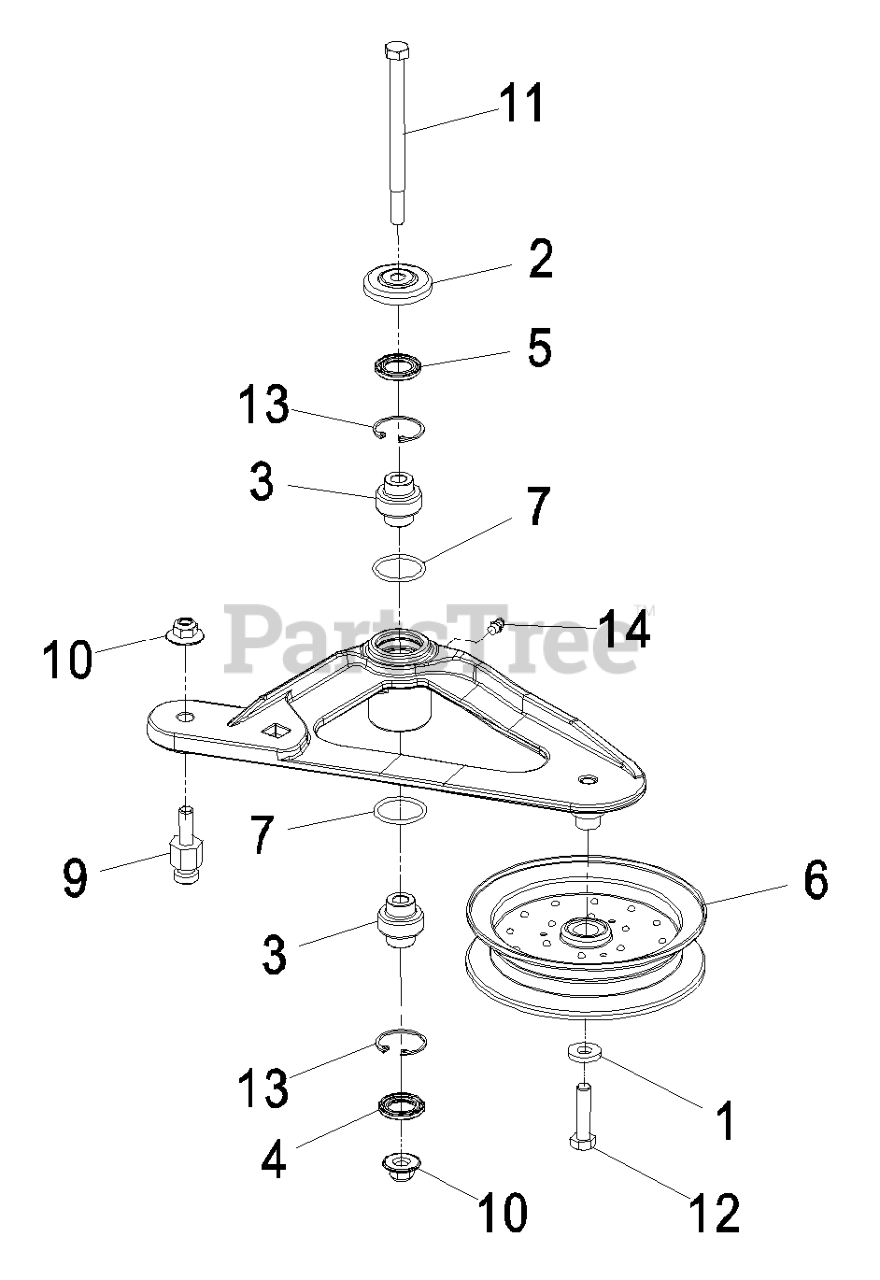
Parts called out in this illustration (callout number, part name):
2	GUARD-TOP
3	BEARING-SPHERICAL
4	SEAL-LIP, DOUBLE
5	SEAL-LIP, SINGLE
10	Nut-Nyloc 3/8-16 Flg
11	SCREW-SHOULDER, HH
12	SCREW-HH
13	RING-SNAP
14	FITTING-GREASE
